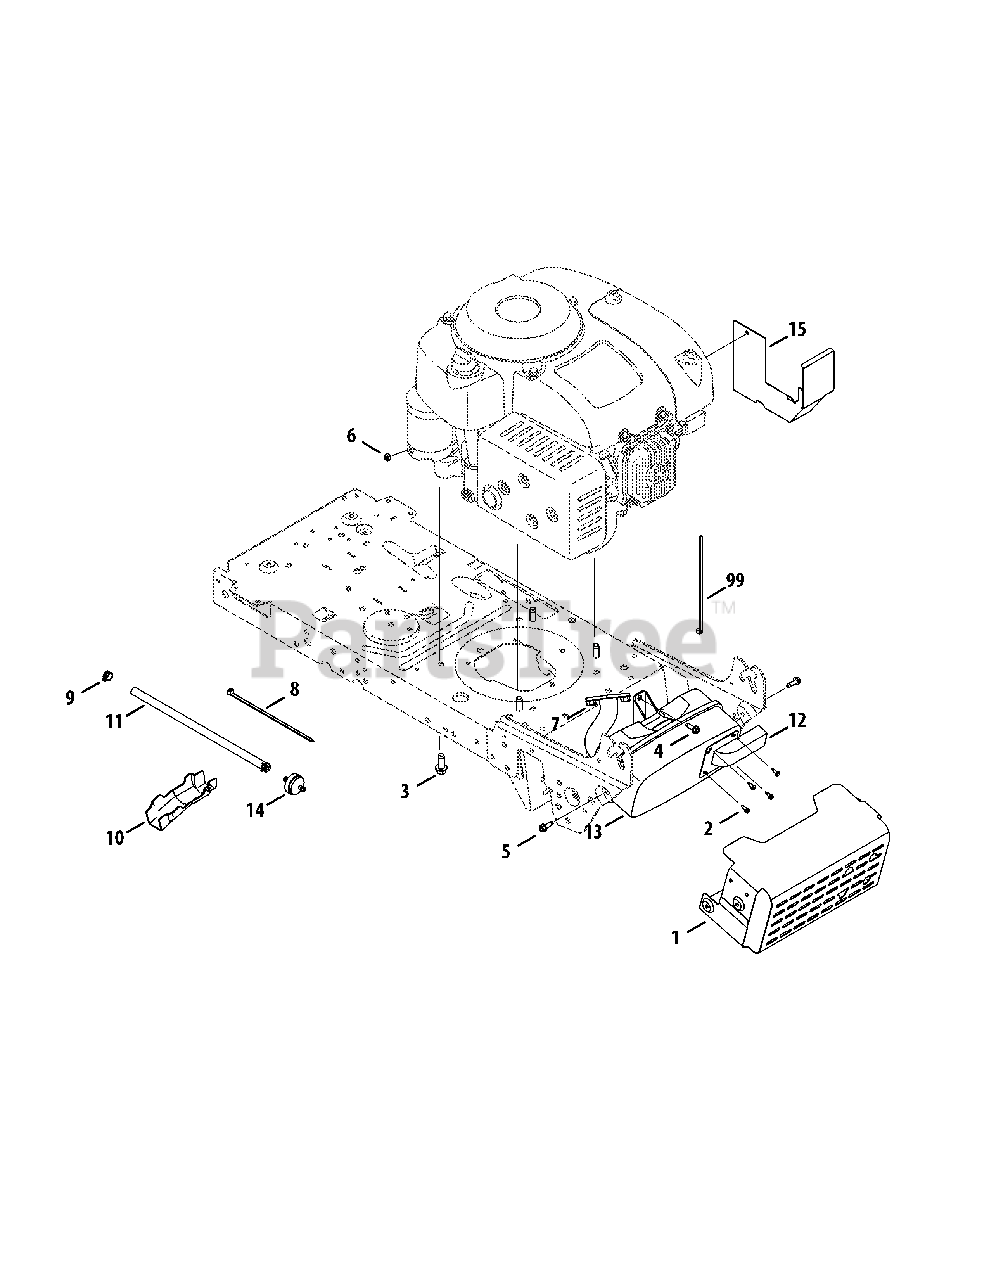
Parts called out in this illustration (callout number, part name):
1	Muffler Sheild
2	Screw, #8-18 x .500
3	Tap Screw, 3/8-16 x 1.000
4	Tap Screw, 1/4-20 x 0.500
5	Tap Screw, 1/4-20 x 0.750
6	Hex Lock Nut, M6-1
7	Flange Nut, M8-1.25
8	Cable Tie
9	Hose Clamp, .490 Dia.
10	Oil Drain Sleeve
11	Low Permeation Fuel Hose, 1/4
12	Muffler Deflector, Long
13	Muffler
14	Fuel Filter
15	Deflector Bracket
